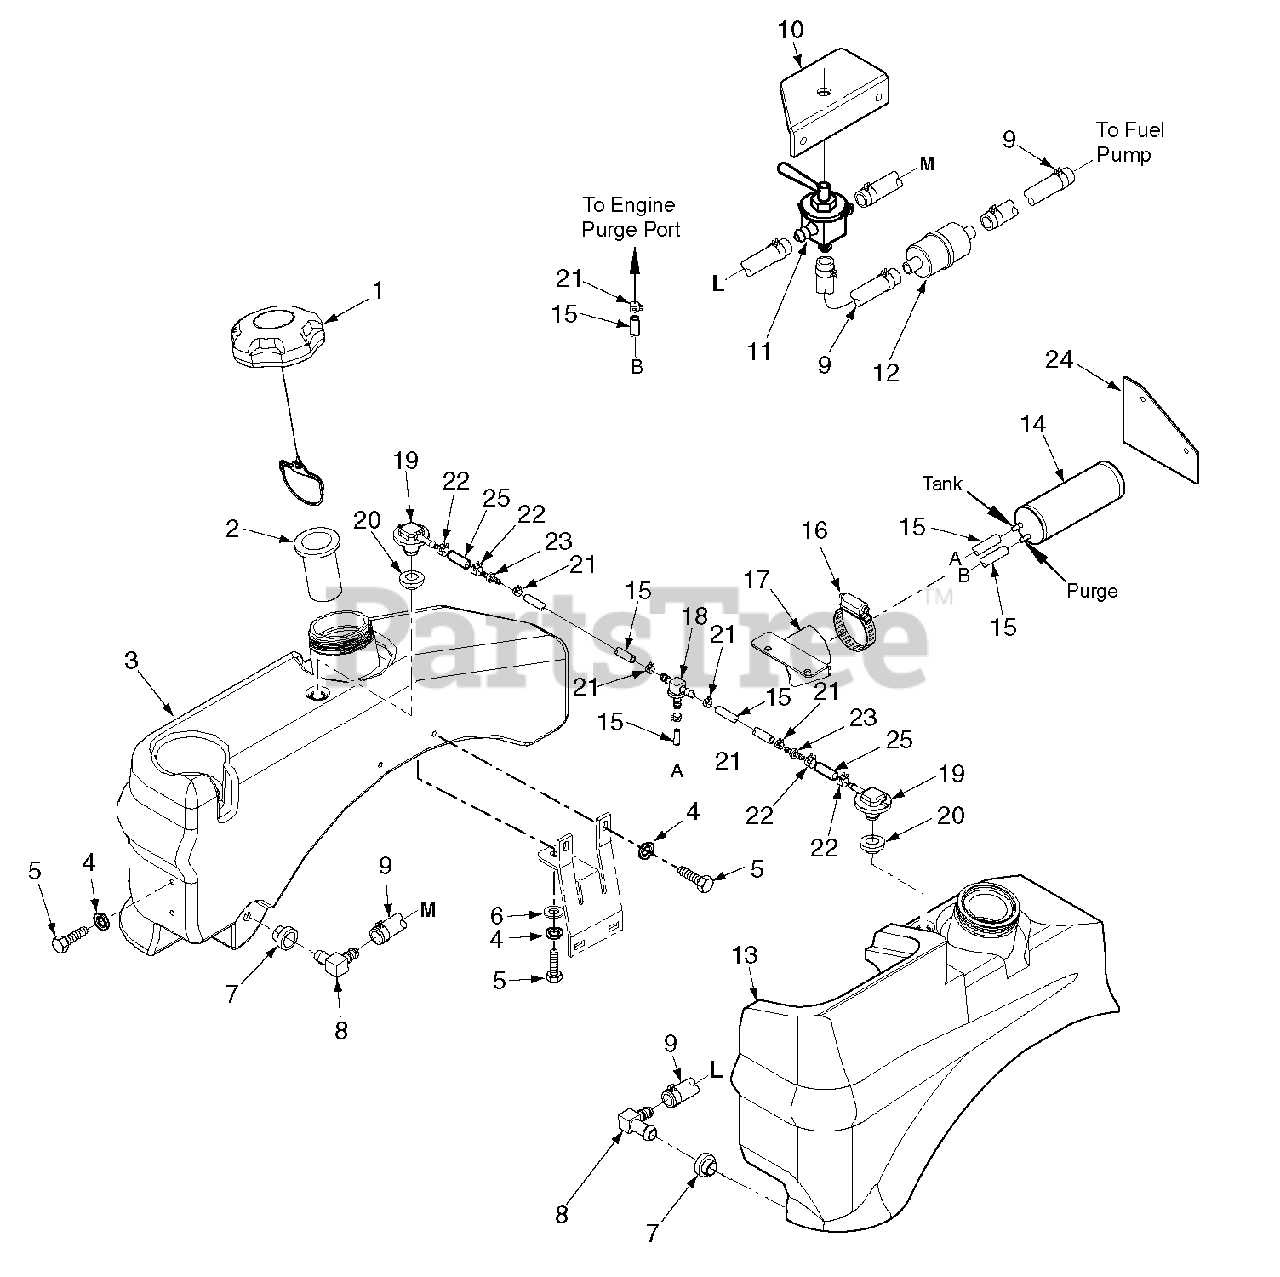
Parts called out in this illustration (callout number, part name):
1	Fuel Cap w/ Tethered
2	Tube, Fuel Tank Insert
3	Fuel Tank RH
4	Lockwasher, 5/16" Spring
5	Bolt, Hex Head 5/16-18 x 3/4"
6	Flatwasher, 5/16-.375 x .875 x .083
7	Tank Bushing
8	Fitting, 90 Degree
9	Fuel Hose, 1/4" I.D. Non-Perm
10	Bracket, Fuel Valve
11	Fuel Shutoff Valve
12	Fuel Filter
13	Fuel Tank LH
14	Carbon Canister
15	Hose, 3/16"
17	Bracket, Canister Mounting
18	T - Fitting, Fuel Vent
19	Valve, Rollover
20	Grommet, Viton
21	Clamp, Vapor Recovery Hose 3/16"
22	Clamp, Fuel Hose
23	Mender, 1/4 x 3/16 w/.02 Hole
24	Heatshield
25	Hose, 1/4" Vapor Recovery
